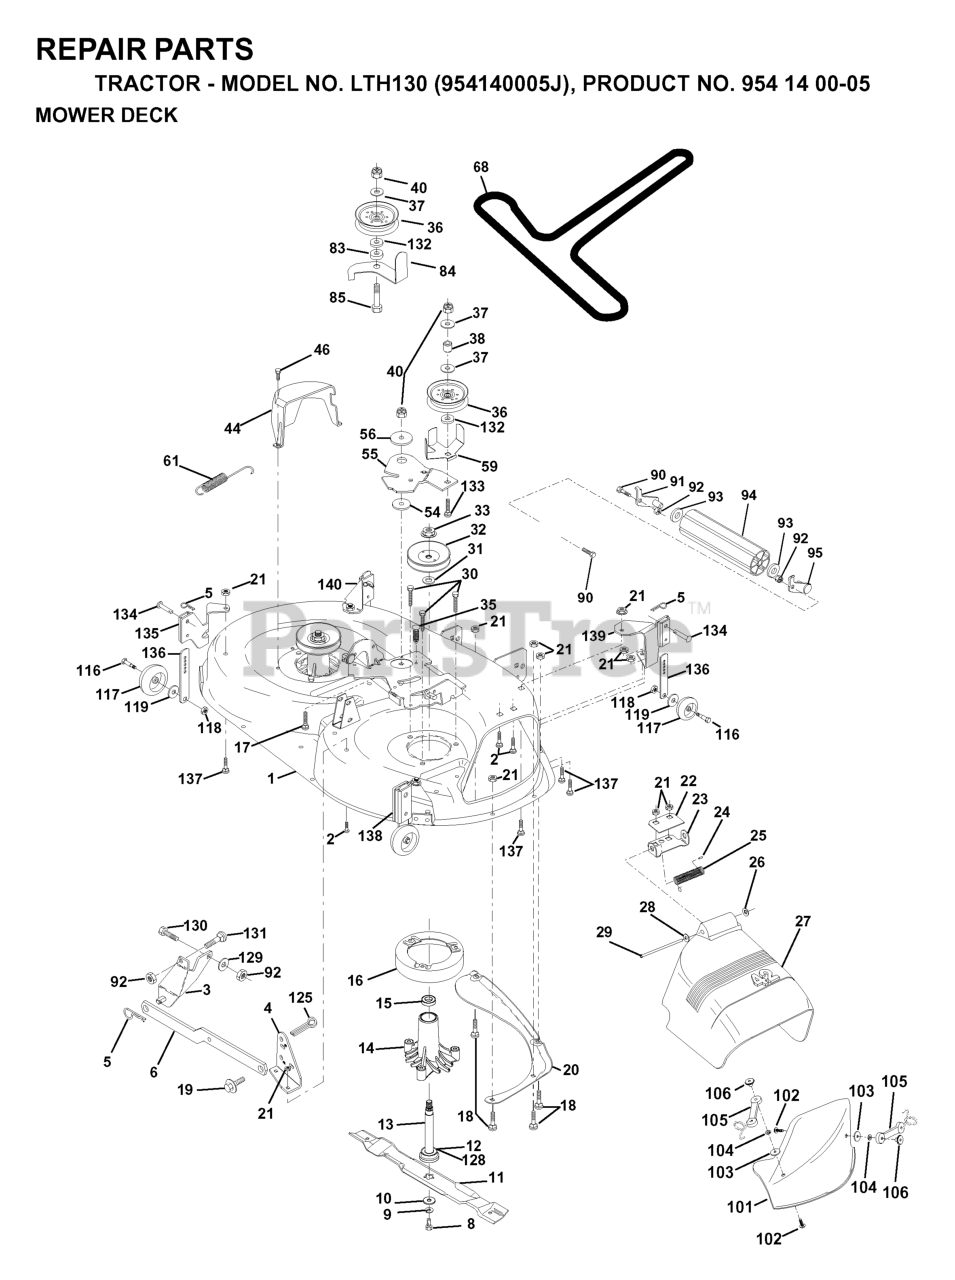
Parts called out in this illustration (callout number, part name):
1	MOWER HOUSING
2	RP BOLT 5/16-18 X3/4 ZN/YEL GR
3	BRKT ASM SWAY BAR
4	BRKT DECK SW BAR
5	RETAINER-SPRNG RB
6	REAR SUSP ARM
8	BLADE BOLT
9	LOCKWASHER
10	WASHER.BLADE
11	BLADE.42".MULCH
12	BEARING.BALL.#6204.(MANDREL)
13	SHAFT ASM VENT
14	HOUSING.MANDREL.VENTED (MACHD)
16	STRIPPER
17	BOLT CARRIAGE
18	BOLT
19	BOLT SHD 5/16-18
20	BAFFLE.VORTEX
21	LOCKNUT
22	STIFFENER BRACKET
23	DEFLECTOR BRACKET
24	CAP-SLEEVE LT
25	SPRING TORSION
26	NUT PUSH M
27	SHIELD.DEFLECTOR.MOWER.42".BLK
28	Washer 11/32 x 5/8 x 16 Ga SD
29	ROD.HINGE
30	SCREW THDROL ROLLING WASHER HD
31	WASHER
32	PULLEY/MANDREL
33	NUT
35	FASTENER.XMAS.TREE
36	FLAT IDLER PULLEY
37	WASHER
38	IDLER SPRING SPACER
44	GUARD MANDREL LH BLACK
46	SCREW.1/4-20X5/8
54	HARDENED WASHER
55	IDLER ARM
56	SPACER RETAINER
59	GUARD, BELT
61	SPRING EXTENSION
68	V-BELT TRIPATH
84	KEEPER.BELT.IDLER
90	BOLT
91	BRACKET LH (A)
92	NUT
93	Washer 1 17/32 X 7/8 X 16 Ga
94	NOSE ROLLER
95	BRACKET RH (B)
101	COVER MULCH 42"
102	SCREW
104	LOCKWASHER #10
105	LATCH ASSY
106	WELDNUT
116	BOLT, SHOULDER
117	WHEEL GAGE DONUT
118	LOCKNUT
119	WASHER.5/16.FLAT.STE.STD.
125	Pin Cotter 1/4 x 1 Plated
128	WASHER FELT
129	WASHER
131	BOLT D
132	Washer 13/32 x 1-3/8 x 13 Ga.
134	RIVET.PIN.HEAD.YELLOW.
135	BRACKET ASSY
136	BAR.ADJUST.WHEEL.ANTI.SCALP.BL
137	BOLT.CARR.5/16-18X5/8.SHORT
138	GAUGE WHEEL BRACKET ASSY
139	BRACKET.WHEEL.GAUGE.FRONT.42
140	BRKT.ASM.WHL.GA.FRONT.LH
